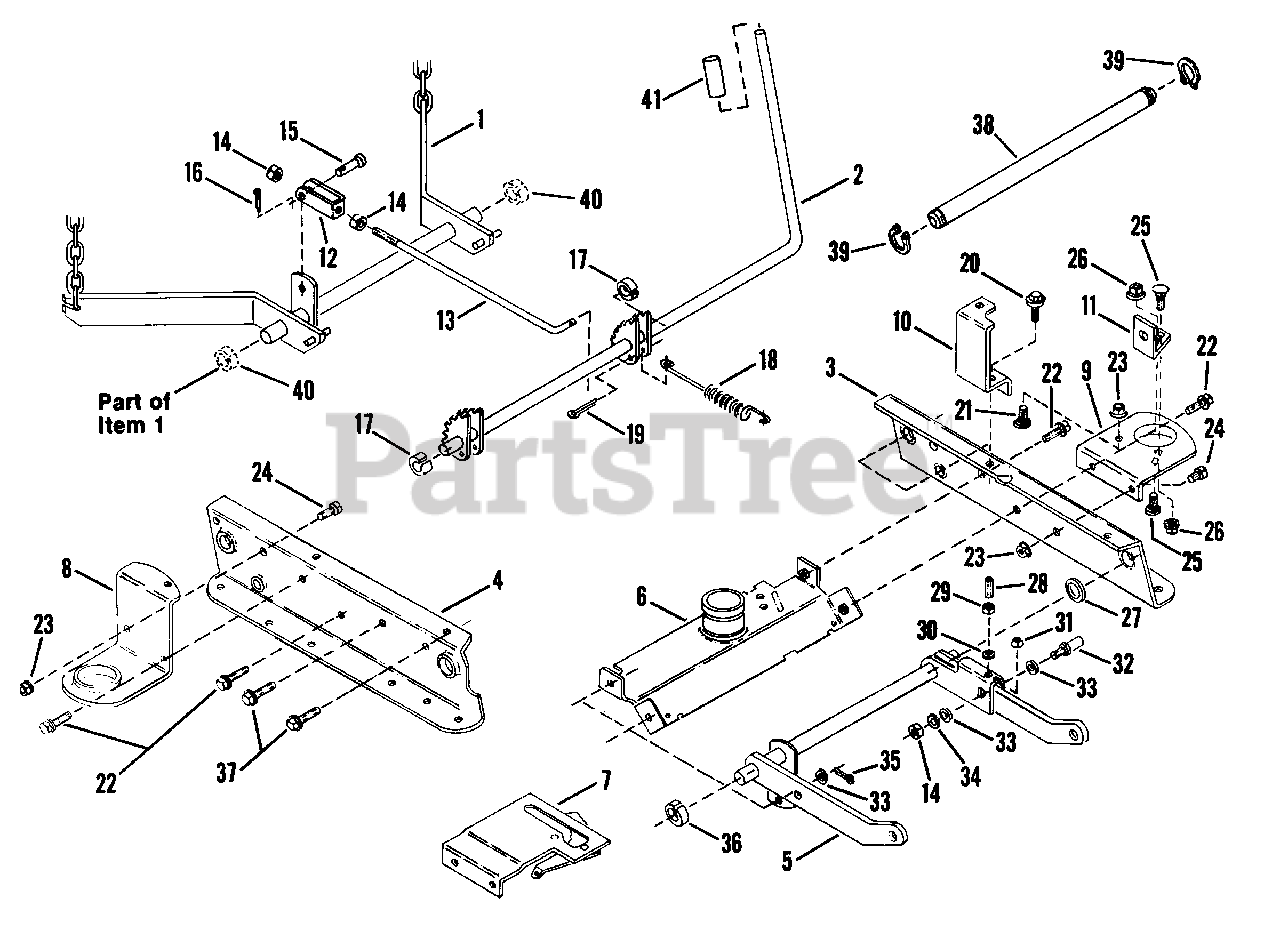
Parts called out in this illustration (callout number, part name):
1	ASSEMBLY, Rear Lift Arm
2	LIFT LEVER STRUCTURE
3	RAIL, Left Half
4	RAIL, Right Half
5	STRUCTURE, Front Lift Arm
6	BRACE, Weldment
7	ASSEMBLY, Clutch Plate
8	SPINDLE, Brace Right Half
9	SPINDLE, Brace Left Half
10	BRACKET, Cover
11	ANCHOR
12	CLEVIS, Timing Rod
13	ROD, Timing
14	NUT, Hex 3/8-24
15	PIN, 3/8 x 1 1/16" Clevis
16	PIN, Cotter 3/32x3/4
17	RING, White
18	SPRING, (CAM-LIFT)
19	PIN, Cotter 5/32x1
20	SCREW, Self-Tapping 1/4-20x5/8
21	SCREW, Cap-Hex Head 3/8-24x1
22	SCREW, Hex Washer Self-Tapping 3/8-16x1
23	NUT, Lock 3/8-24
24	SCREW, Cap-Hex Head 3/8-24x3/4
25	BOLT, Carriage 5/16-18x3/4
26	NUT, Hex Flange Lock 5/16x18
27	WASHER, (Spacer)
28	SCREW, Set-Hex Socket 5/16-18x1 1/4
29	NUT, Jam-Hex 5/16-18
30	WASHER, SAE 5/16-18
31	NUT, Hex 5/16-18
32	PIN, Shoulder Bolt
33	WASHER, 3/8
34	WASHER, Lock 3/8
35	PIN, Cotter 1/8x3/4
36	RING, Red
37	SCREW, Hex Washer Self-Tapping 5/16-18x5/8
38	SUPPORT, Rod
39	RING, 5/8" External Retaining
40	RING, Blue
41	GRIP, Height Adjustment Lever
